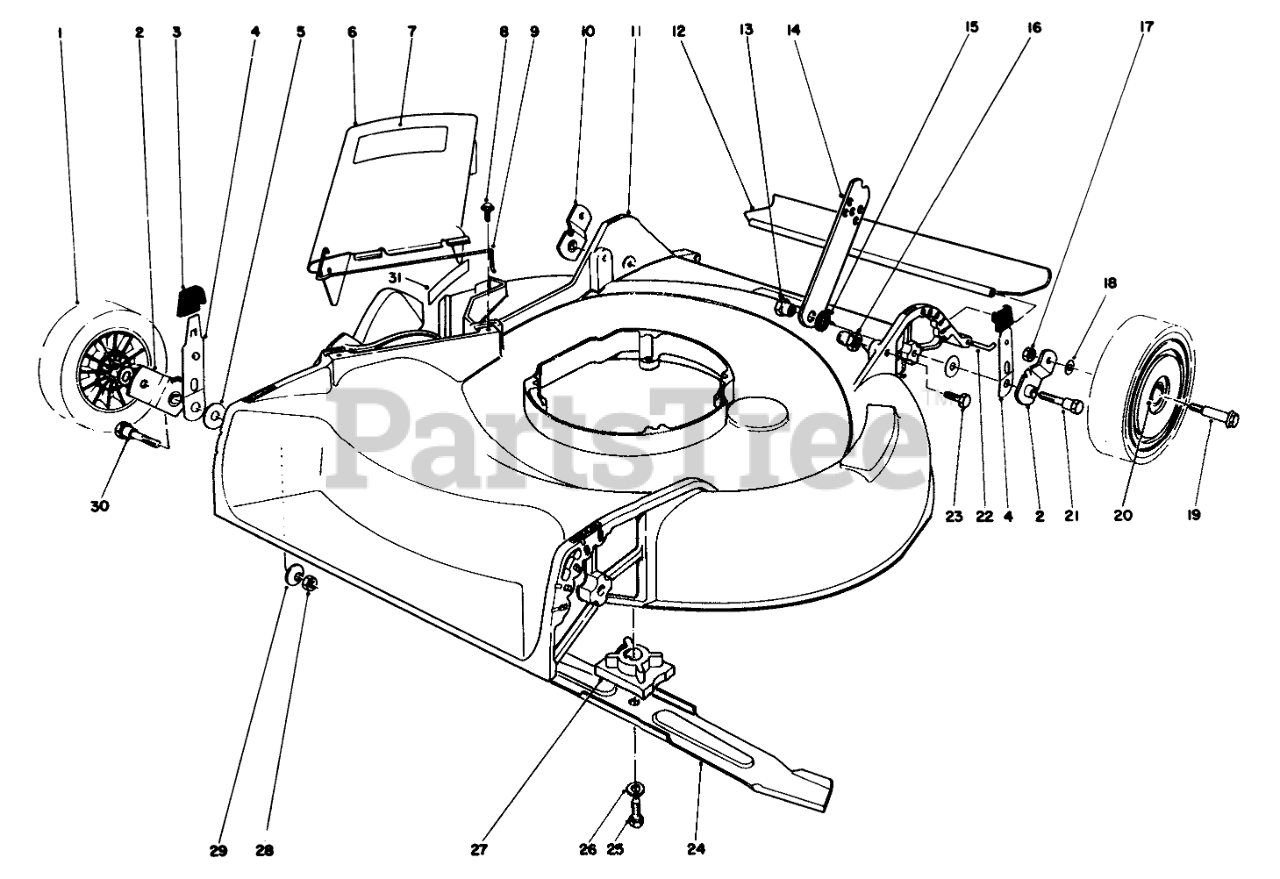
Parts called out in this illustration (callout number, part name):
1	Wheel & Tire Assembly (Incl. Ref. #20)
2	Pivot Arm
3	KNOB-ARM
4	SPRING ARM ASM
5	Washer
6	Deflector Assembly (Incl. Ref. #7)
7	Decal-Danger
8	SCREW-HWH
9	SPRING HINGE
10	Pivot Arm
11	HOUSING ASSEMBLY
12	REAR SAFETY SHIELD 21
13	HANDLE PIVOT NUT
14	HANDLE LATCH
15	SPACER
16	HANDLE PIVOT NUT
17	Nut
18	WASHER
19	BOLT-WHEEL
20	BUSHING
21	PIVOT SCREW
22	SHIELD ROD
23	SCREW-HH
24	Blade
25	SCREW-HH
26	WASHER-LOCK
27	BLADE RETAINER
28	NUT-LOCK, NI
29	WASHER-BELLEVILLE
30	5/16-18 PIVOT SCREW
31	DANGER DECAL
